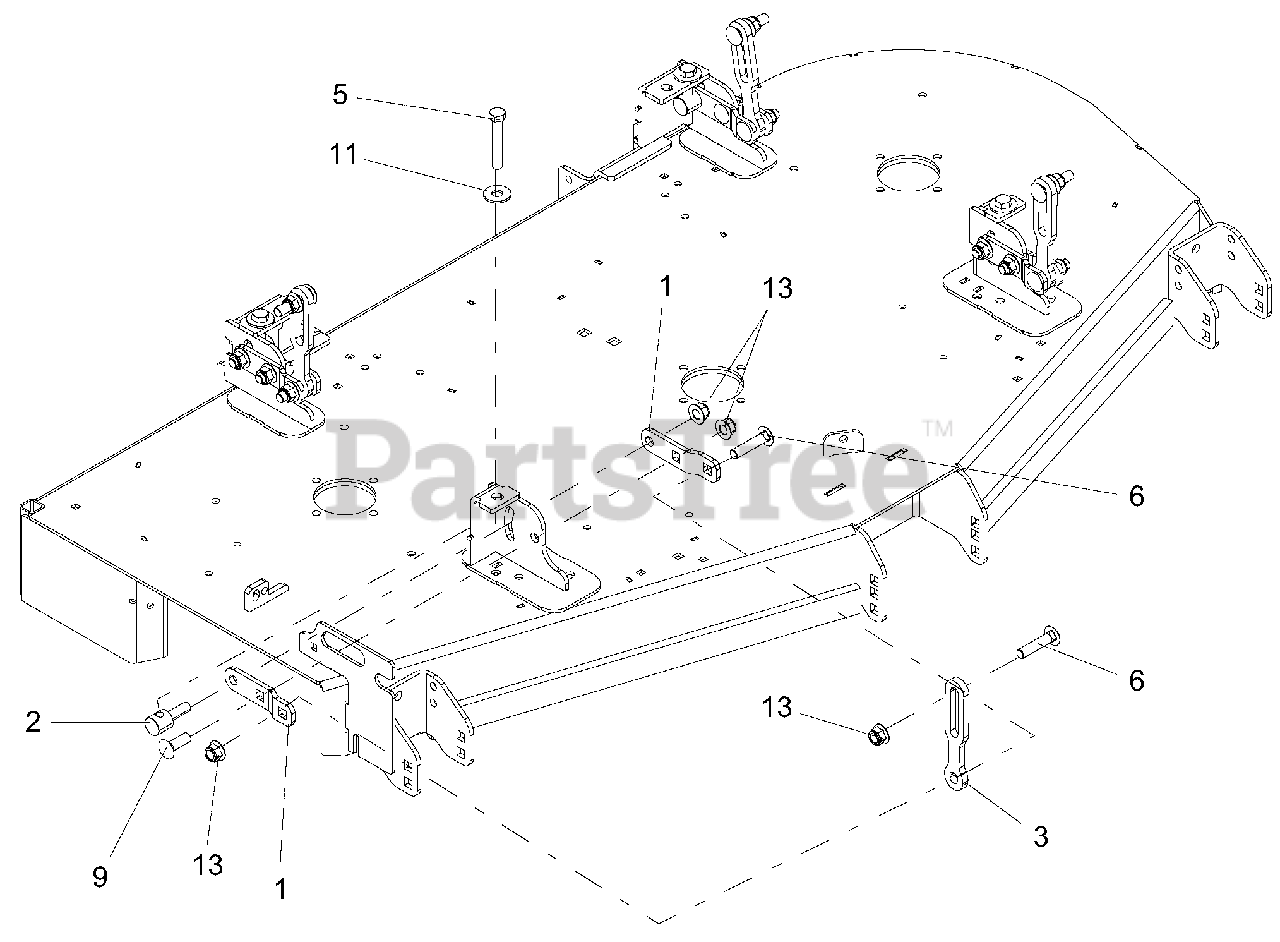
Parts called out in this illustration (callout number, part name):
1	BRKT, DECK LEVELING
2	TRUNNION, .50-13
3	LINK, DECK LIFT
5	BLT-HEX .50-13X3.0 GR5 FTD YWZ
6	BLT-RDHDSQNK .50-13X2.25YG5
9	BLT-RDHDSQNK .50-13X1.50 G5 YWZC
11	WSHR-FL-STL.563X1.38X.109YWZC
13	NUT-LK-NYL-FLG .50-13 YWZC
